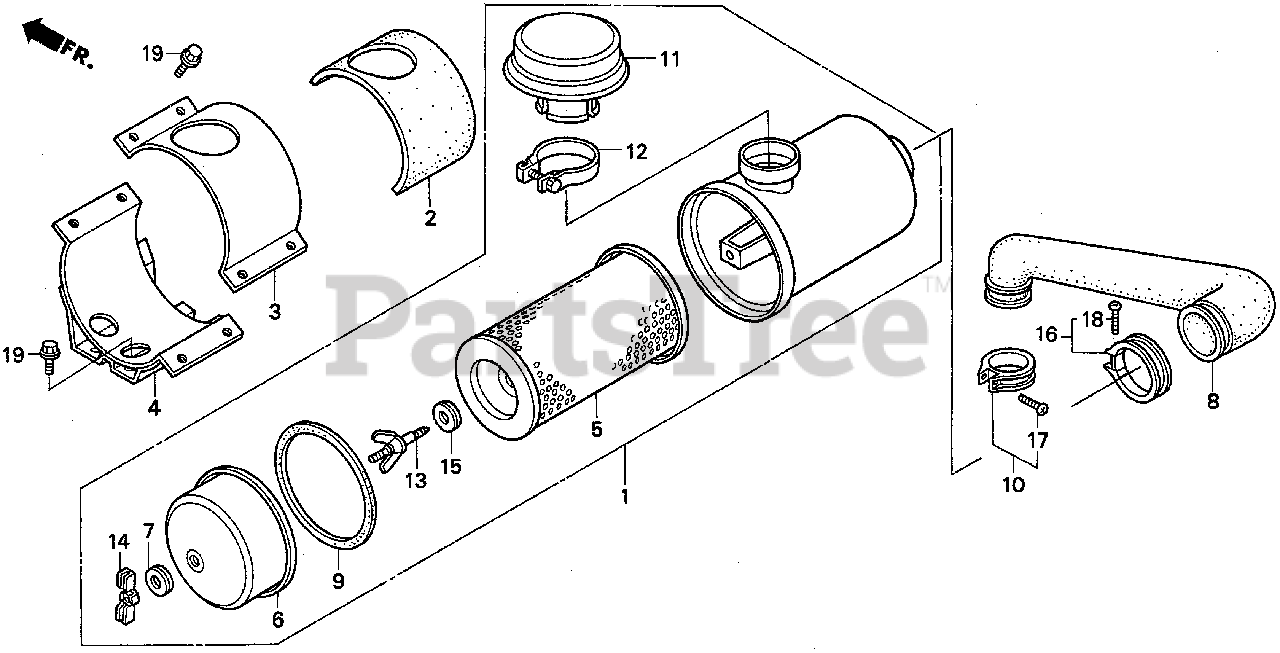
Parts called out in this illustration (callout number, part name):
1	AIR CLEANER ASSY.
2	RUBBER, AIR CLEANER HOLDER (UPPER)
3	HOLDER, AIR CLEANER (UPPER)
4	HOLDER, AIR CLEANER (LOWER)
5	ELEMENT, AIR CLEANER
6	COVER, AIR CLEANER
7	GROMMET, AIR CLEANER
8	TUBE, AIR CLEANER CONNECTING
9	SEAL, AIR CLEANER
10	BAND, AIR CLEANER CONNECTING TUBE
11	CAP, IN.
12	CLAMP ASSY.
13	BOLT, AIR CLEANER
14	WINGNUT (6MM)
15	WASHER, AIR CLEANER
16	BAND, AIR CLEANER CONNECTING TUBE (50)
17	SCREW, PAN (4X20)
18	SCREW, PAN (4X25)
19	BOLT, FLANGE (6X12)
